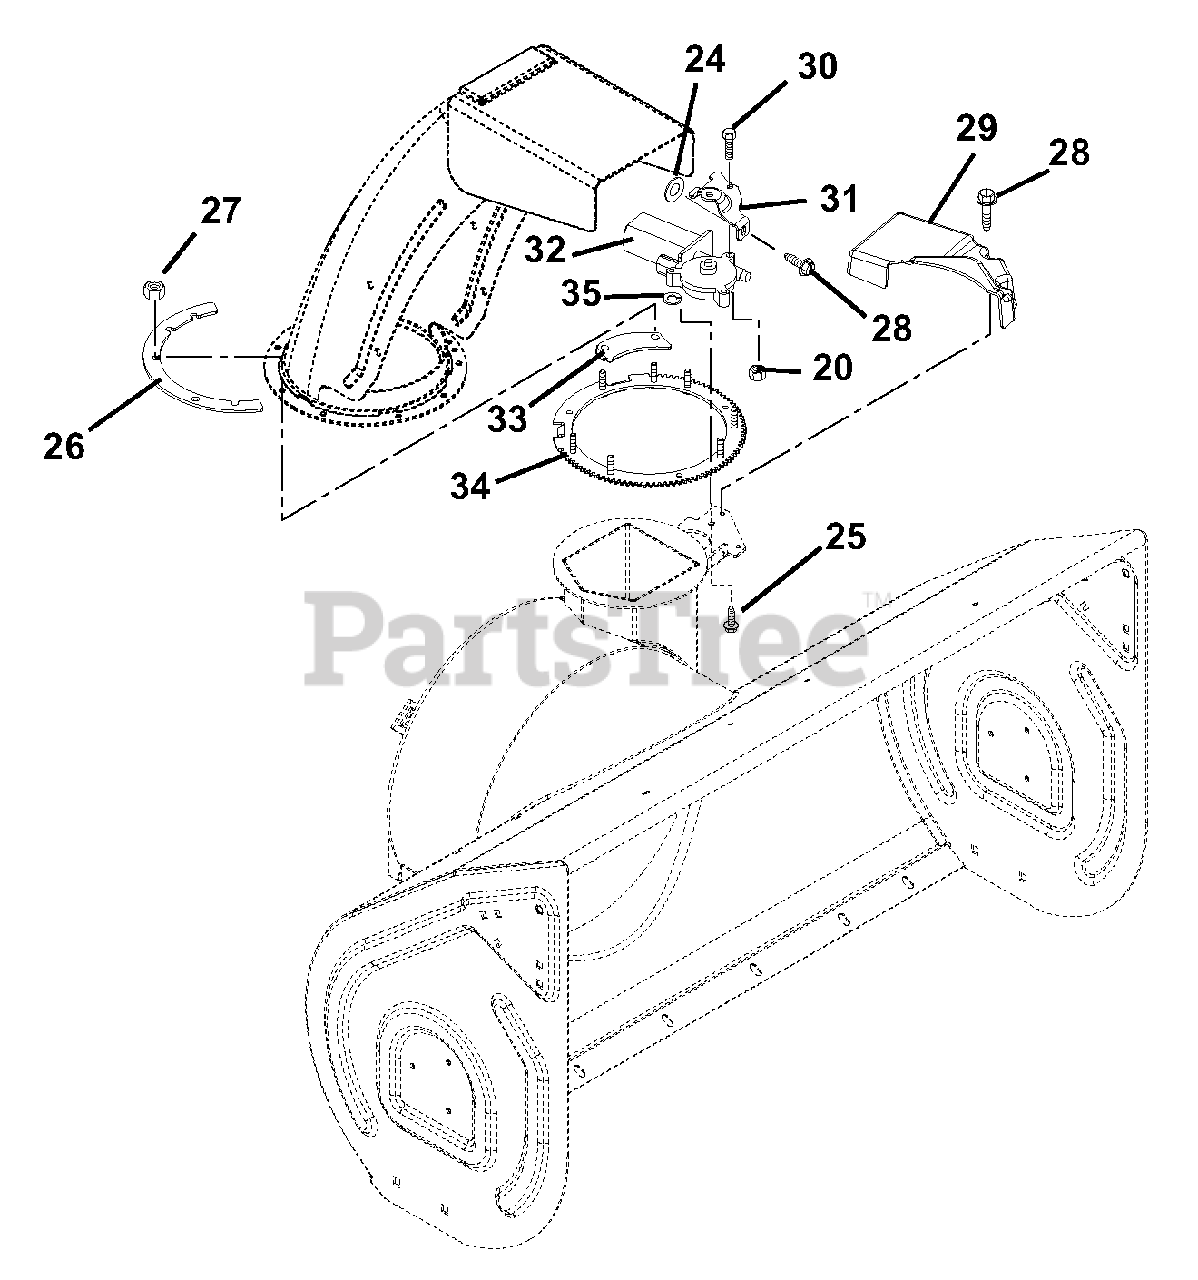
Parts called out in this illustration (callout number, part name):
20	@NUT-LK-CTR .25-20 YWZC
24	@WSHR-FL-STL.281X.62X.065 YWZC
25	@SCR-TAP .31-18X.75 HWH TR YWZ
26	RING, COVER
27	@NUT-SPNLK-FLG .25-20 YWZC
28	@SCR-TAP 12-24X.50 HWH TR YWZC
29	COVER, MOTOR
30	@BLT-HEX .25-20X1.25 GR5 YWZC
31	BRACKET, ELECTRIC MOTOR
32	MOTOR, ELECTRIC CHUTE
33	CLAMP, CHUTE
34	GEAR, CHUTE
35	@WSHR-LK .31X.078 REG YWZC
